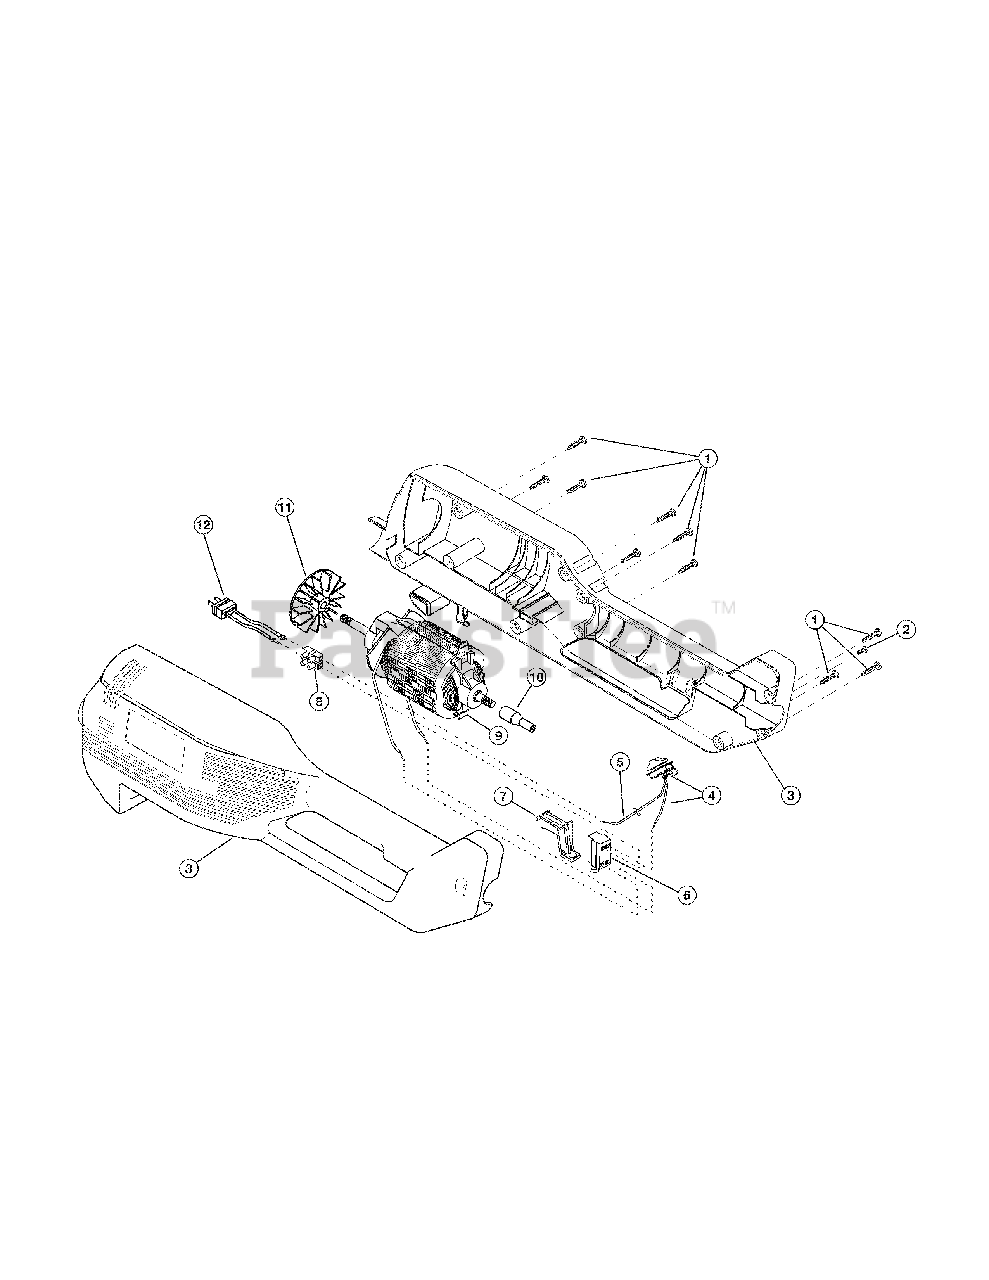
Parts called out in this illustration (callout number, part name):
1	Screw, Housing Set
2	Anti-Rotation Screw
3	Motor Housing Assembly
4	Two-Speed Switch Assembly
5	Lead Wires
6	Switch (includes 7)
7	Trigger
8	Terminal Block
9	Motor Assembly (includes 10-11)
11	Cooling Fan
12	Power Cord Assembly
